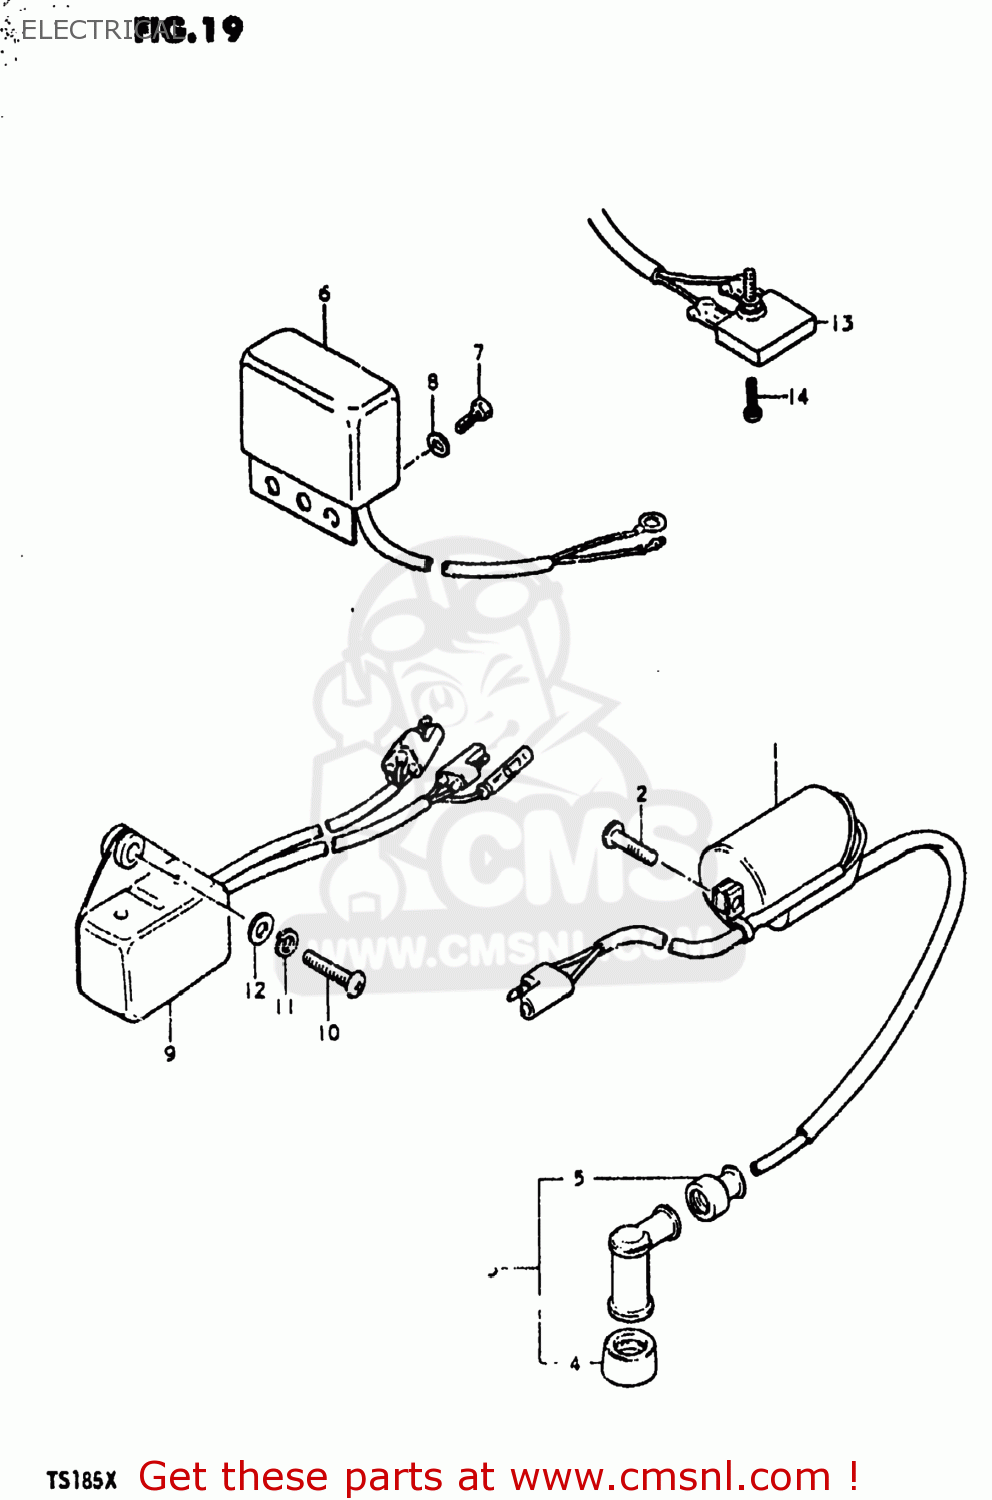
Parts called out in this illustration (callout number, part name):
1	COIL ASSEMBLY,IGNITION
2	SCREW 5X20
3	CAP,SPARK PLUG
4	SEAL,SPARK PLUG
5	SEAL,SPARK PLU
6	REGULATOR ASSEMBLY
7	SCREW(5X12)
8	WASHER
9	CDI UNIT
10	SCREW
11	LOCK WASHER
12	WASHER
13	RECTIFIER ASSEMBLY
14	SCREW
